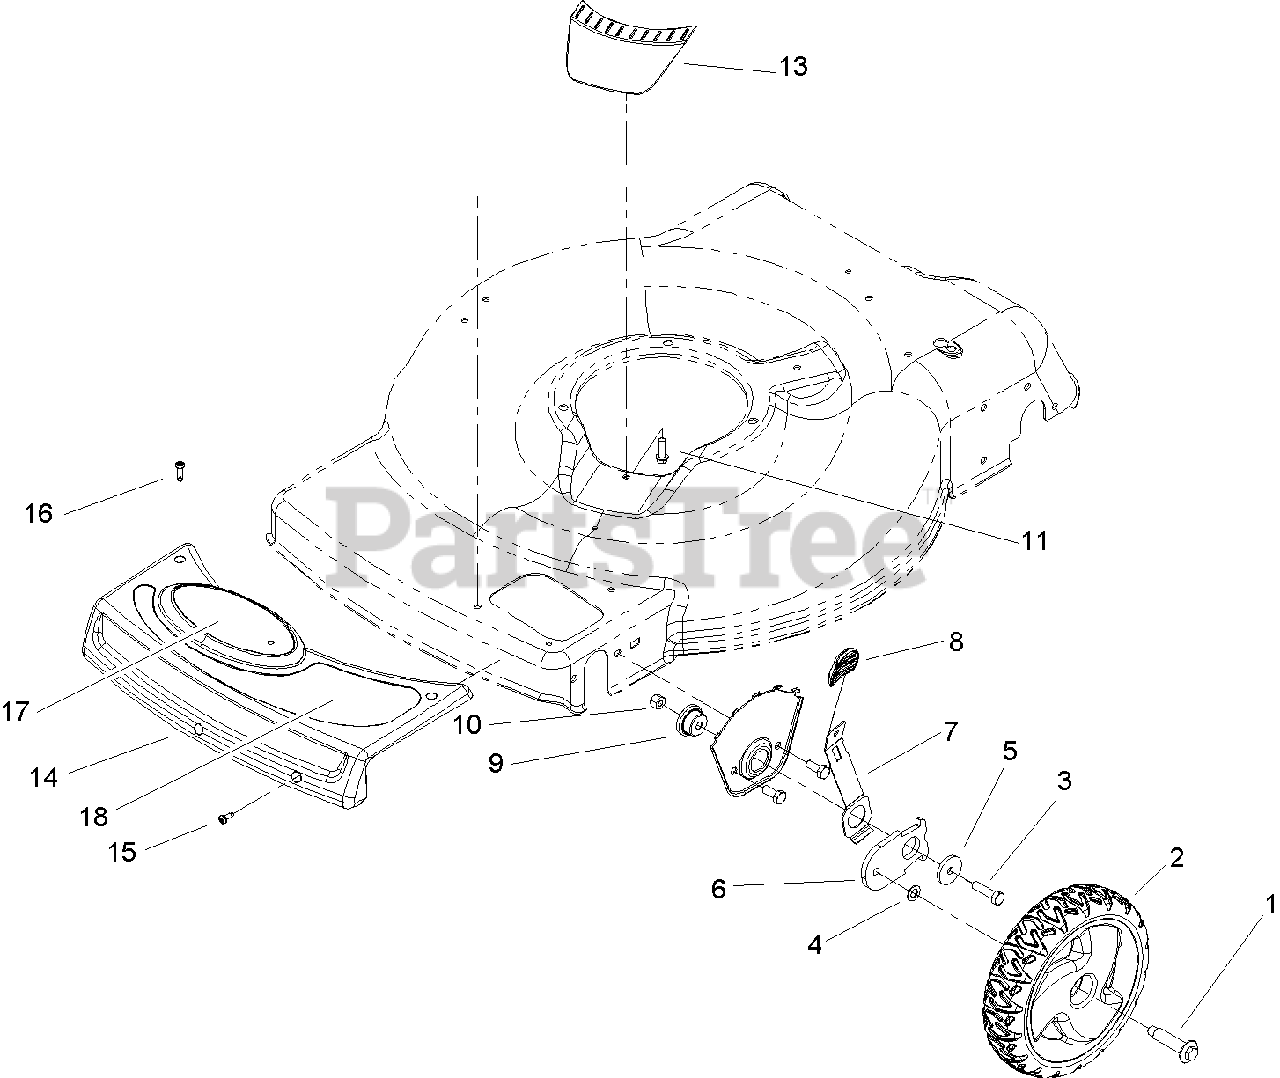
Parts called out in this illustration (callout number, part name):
1	BOLT-SHOULDER
2	8IN WHEEL ASM
3	SCREW-HH
5	Washer-Flat
6	ARM-PIVOT, FRONT
7	Arm-Spring
8	KNOB-LEVER, HOC
9	Bushing-Mount, HOC
10	NUT-LOCK, NI
11	SCREW-HWH
13	COVER-BELT OPENING
14	BUMPER-WPM
15	SCREW-THREAD FORMING
17	DECAL-HOUSING
18	DECAL-HOUSING
